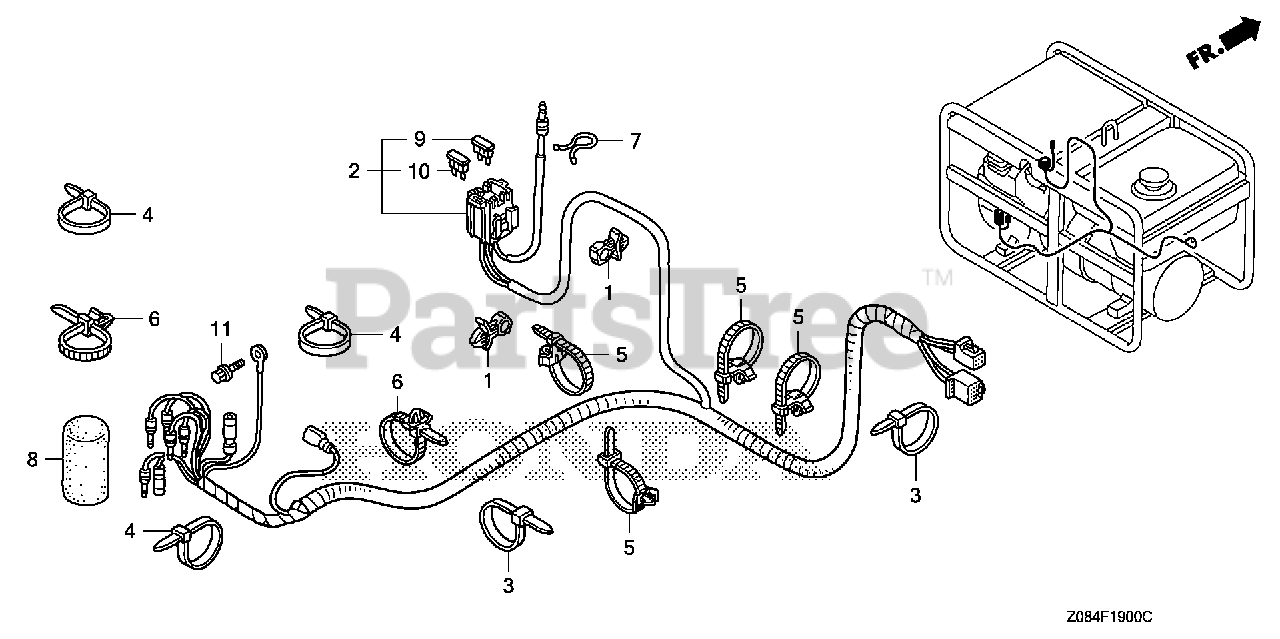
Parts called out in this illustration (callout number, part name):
1	CLIP, IGNITION WIRE (BLACK IN.D=7.0MM)
2	WIRE HARNESS ASSY., ENGINE
3	TIE, CABLE
4	TIE, CABLE (C)
5	BAND, WIRE HARNESS (150MM) (NATURAL)
6	BAND, WIRE HARNESS (150MM) (BLUE)
7	PURSE, LOCK (8MM)
8	TUBE, CORD (30MM)
9	FUSE, BLADE (5A)
10	FUSE, BLADE (10A)
11	BOLT, FLANGE (6X12)
